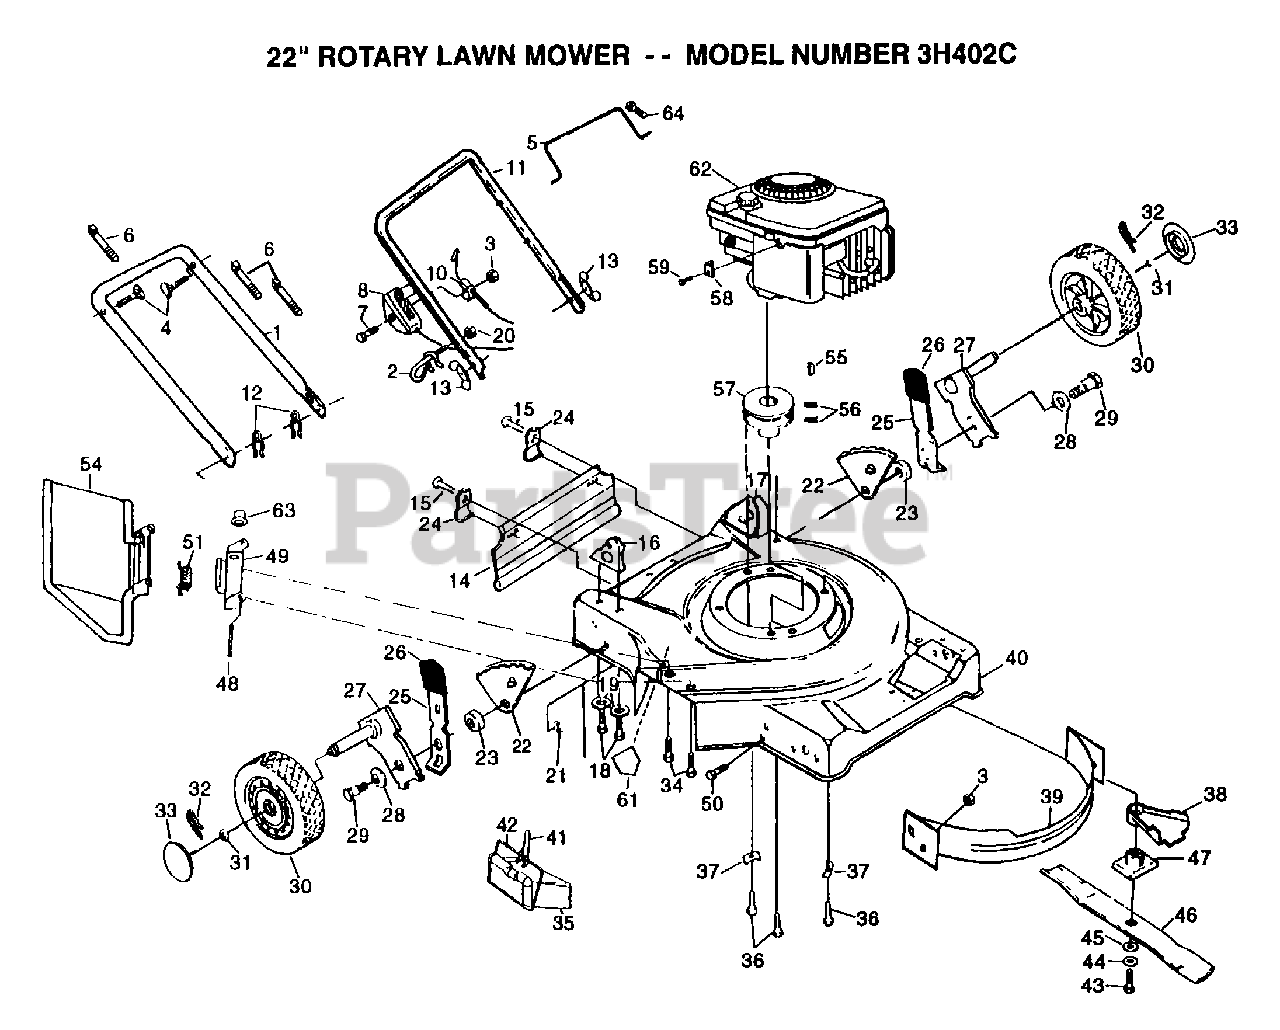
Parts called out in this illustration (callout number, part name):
2	ROPE GUIDE
4	BOLT.HANDLE.LM
5	CONTROL BAR
7	SCREW.HXHD.WASH.
8	"CONTROL, THROTTLE"
10	"CABLE,ENG ZONE CO"
12	HAIRPIN COTTER
13	"NUT,WING PM"
14	SKIRT.REAR.FGD.22
15	TAPPING SCREW
18	SCREW
19	STEEL WASHER
20	NUT
21	LOCKNUT PM
22	BRACKET.ADJ.9POS.
24	"BRKT,DEFL PM"
25	SPRING SELECTOR
26	KNOB PM
27	AXLE ARM
28	"WASHER, BELLEVIL."
29	BOLT SHLD 3/8-16
31	WASHER
32	RETAINER CLIP PM
33	HUB CAP
34	SCREW
36	SCREW
39	BAFFLE FRONT 22SD
40	KIT.HSG.22SD.FWGD
41	LATCH.PLUG.22SD
42	BAIL.PLUG.MUL.22.
43	SCREW
44	LOCKWASHER
45	"WASHER,HARDEN"
46	"BLADE.MULCH.22"""
47	ADAPTOR.BLADE.LM
48	"ROD,HINGE "
49	"BRKT,HSG"
50	SCREW
51	"SPRING,TORSION"
55	HI PRO KEY PM
56	SCREW
57	ENGINE.PULLEY.FWG
58	CABLE CLAMP
59	SCREW PM
61	DECAL HYT
63	PUSH ON SPEED NUT
64	"SCREW,PAN HD"
